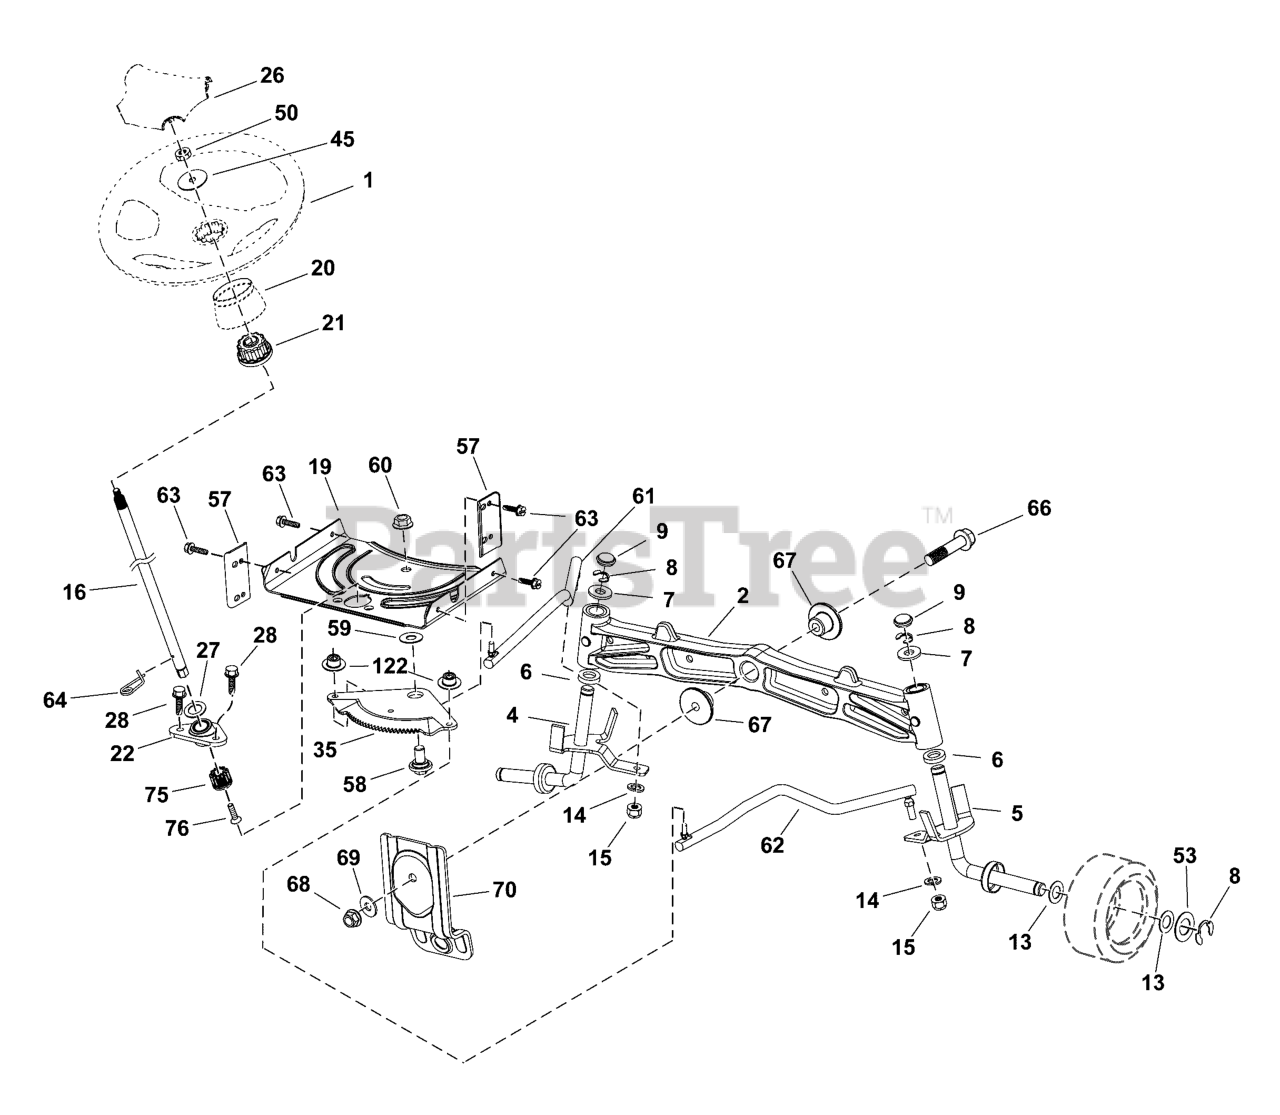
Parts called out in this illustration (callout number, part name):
1	Wheel, Steering
2	ASSEMBLY, Front Axle
4	Spindle Asm., LH
5	Spindle Asm., RH
6	BEARING, Race Thrust Harden
7	Washer 25/32 x 1-5/8 x 16 Ga.
8	RING, Clip #T5304-75
9	Cap, Spindle
13	Washer 25/32 x 1-1/4 x 16 Ga.
14	WASHER, 3/8, SLW ZD
15	Nut, Crown Lock 3/8-24 unf
16	SHAFT, Steering
19	Plate Steering
20	Boot, Steering
21	ADAPTER, Steering Wheel
26	Insert, Wheel Steering
28	Screw 3/8-16 x .75 Smgml Tap/R.Z
35	Gear, Sector Plate
45	COVER-CYLINDER HEAD
50	NUT, 3/8-16, Lock
53	WASHER, Hardened
57	Bracket Upstop
58	Bolt Shoulder Sector Pivot CFM
59	Washer Thrust Sector Steering
60	Nut Flange Lock 5/8-11
61	Draglink, LH
62	Draglink, RH
63	Screw 5/16-18 X 3/4 Smgml Tap/Bl
64	Retainer Clip Spring Steering
66	Bolt Hex Fghd 7/16-14 x 3 Serr
67	Bushing PM Front Axle
68	Nut Lock Flange 7/16-14 Gr. 5
69	Washer 1.5 x .505 x .118
70	BRACKET, Deck Susp. Front
76	SCREW, Socket Head
122	Cap Gear Sector
